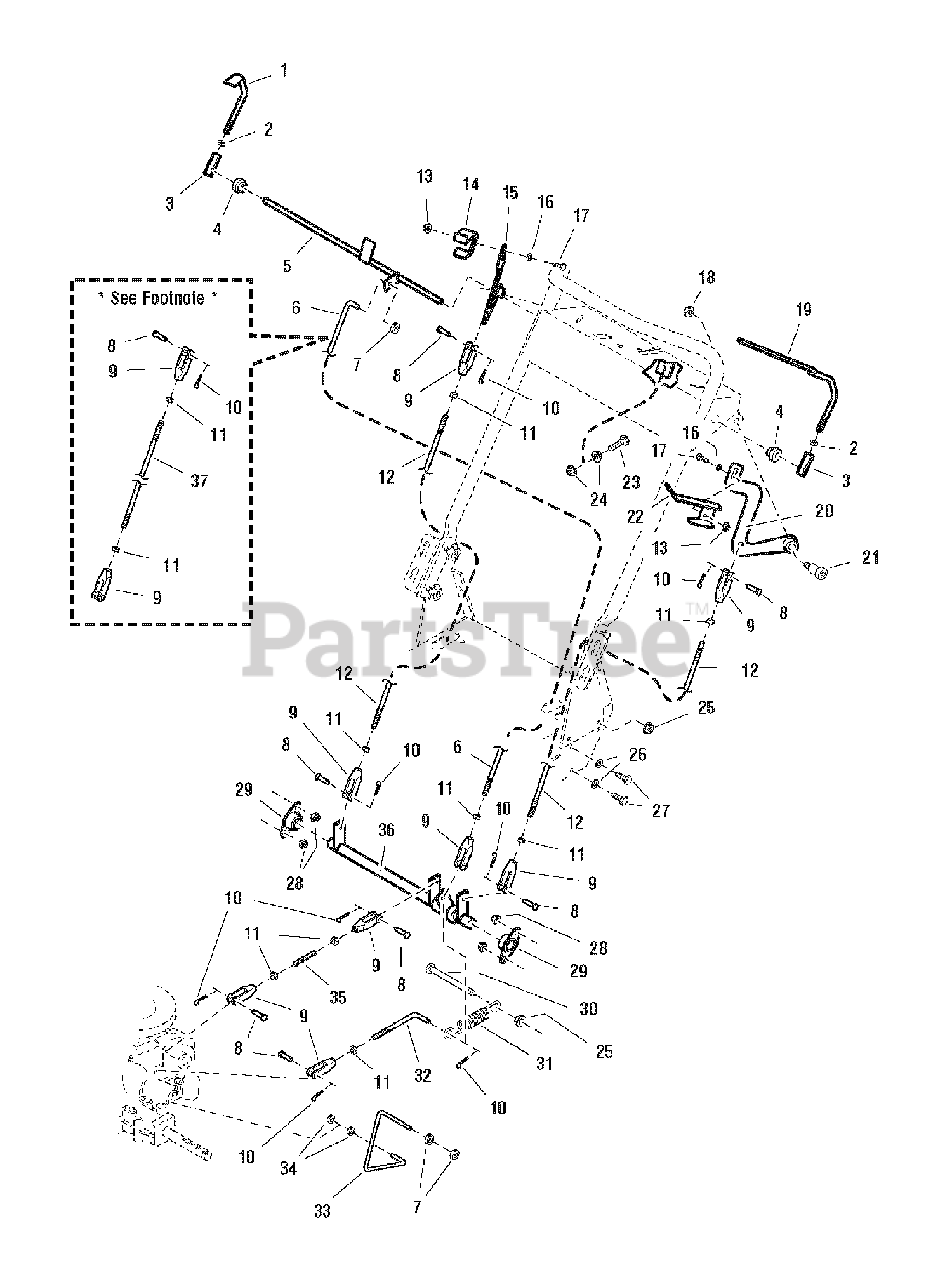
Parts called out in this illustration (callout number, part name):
1	OPERATOR PRESENCE HANDLE - RH
2	NUT, Hex, 3/8-16
3	ADJUSTER LINKAGE
4	SHOULDER SPACER
5	SWITCH ROD
6	* See Footnote *
7	COLLAR, Set, 5/16
8	PIN, Clevis, 5/16 x 1
9	CLEVIS, Plastic, 5/16-24
10	PIN, Cotter
11	NUT, Hex, 5/16-24
12	THUMB CONTROL ROD
13	NUT, Hex Serrated Flange, 1/4-20
14	THUMB PLATE - RH
15	PIVOT CONTROL - LH
16	WASHER, Lock, 1/4
17	CAPSCREW, Hex Head, 1/4-20 x 5/8
18	NUT, Hex Side Lock, 3/8-16
19	OPERATOR PRESENCE HANDLE - LH
20	PIVOT CONTROL - RH
21	SHOULDER BOLT, 1/2 x 1
22	THUMB PLATE - LH
23	CAPSCREW, Hex Head, 5/16-18 X 1-1/4"
24	NUT, Hex Serrated Flange, 5/16-18
25	NUT, Hex Serrated Flange, 3/8-16
26	WASHER, 5/16
27	BOLT, 5/16-18 X 3/4 GD5
28	NUT, Hex Nylon Lock, 5/16-18
29	BEARING, Flange
30	BOLT, 3/8-16 X 4" GD5 CZ
31	SPRING, Extension
32	BRAKE LINKAGE ROD
33	DUMP VALVE ROD
34	COLLAR, Set, 1/4
35	LINK STUD
36	CONTROL SHAFT ASSEMBLY
37	BRAKE LINKAGE ROD
